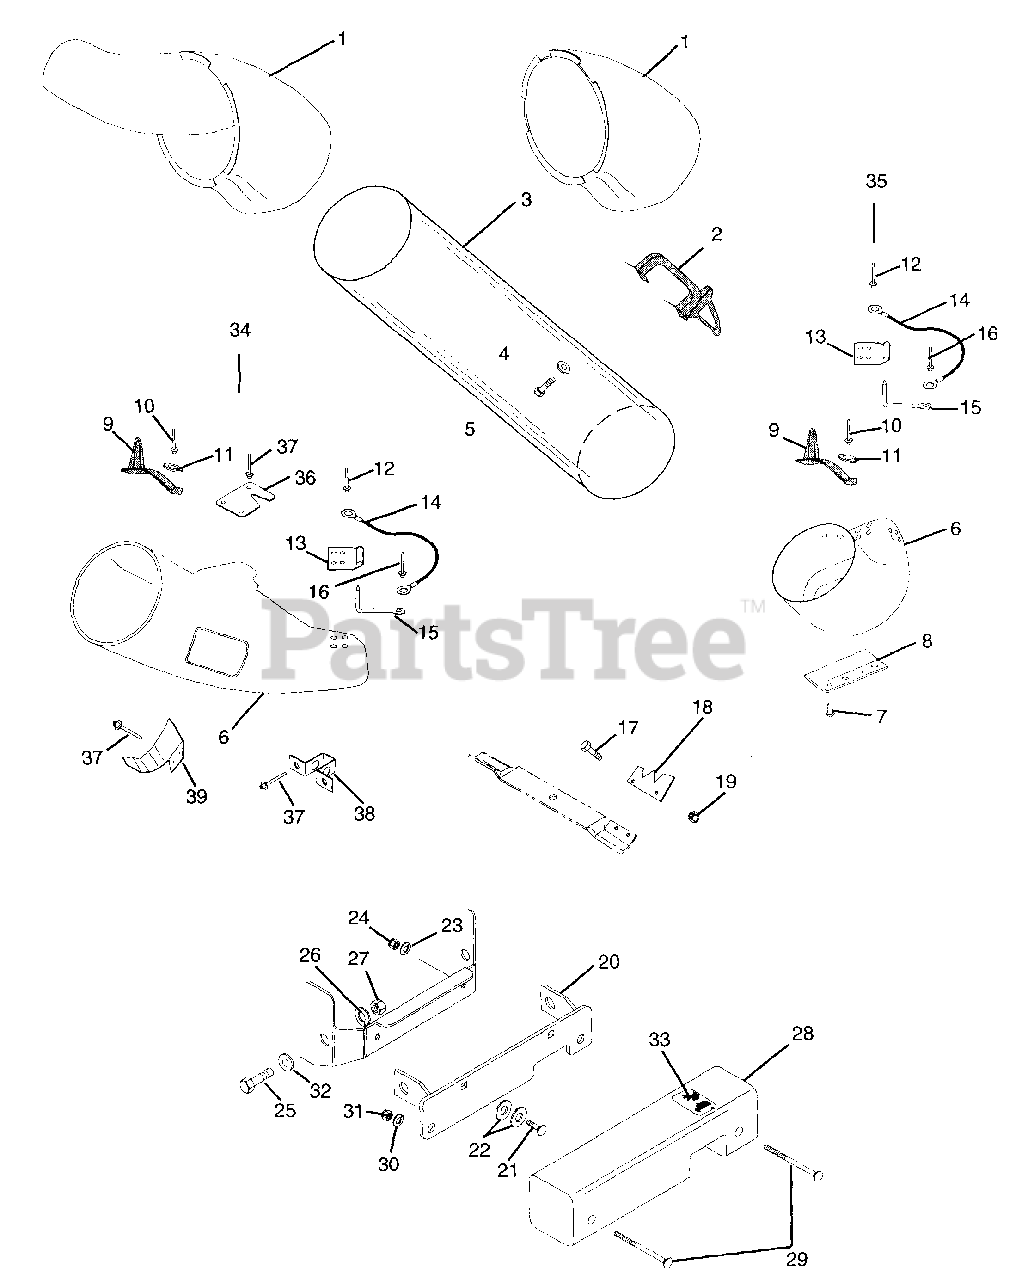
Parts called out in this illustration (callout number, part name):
1	BAGGER BOOT
1	BAGGER BOOT - UPPER
2	TUBE HANDLE
3	BAGGER TUBE
4	WSHR-FL-STL .268X.562X.046 PL
5	SCR-TAP 10-16X .75 HWH PL SD
6	PAN BOOT ASSEMBLY
7	RVT-TBLR .187X.375 OH ST PL
8	EXTENSION CHUTE
9	TUBE RETAINER
10	RVT-POP.187X.527 DOME ST
11	WSHR-FL-STL .194X.492X.047 PL
12	RVT-POP .187X.402 DOME ST
13	BOOT BRACKET
14	LANYARD
15	PULL PIN
16	RVT-TBLR .187X.375 ST-AL PL
17	BLT-HEX .31-24X.75 GR8
17	BLT-HEX .38-16X2.00 GR8
18	SERVICE VANE PACKAGE
19	NUT-LK TOP .312-24 PL GR C
20	ADAPTER
21	BLT-RDHDSQNK .38-16X1.0 PL
22	WSHR-FL-STL .38X.875X.083 PL
23	WSHR-LK .375X.094 MED PL
24	NUT-HEX .375-16
25	BLT-HEX .62-11X1.25 PL GR5
26	WSHR-LK .625X.156 MED PL
27	NUT-HEX .625-11
28	COUNTER WEIGHT
29	BLT-RDHDSQNK .44-14X4.50 PL
30	WSHR-LK-INT .438 YWZC
31	@NUT-HEX .44-14 YWZC
32	WSHR-FL-STL.656X1.312X.095 PL
33	DECAL- HOT SURFACE SYMB.
34	MOWER BOOT ASSY- 32"
35	MOWER BOOT ASSY- 40"
36	BOOT SUPPORT
37	RVT-POP.187X.277 DOME ST
38	STRAP
39	BAFFLE
